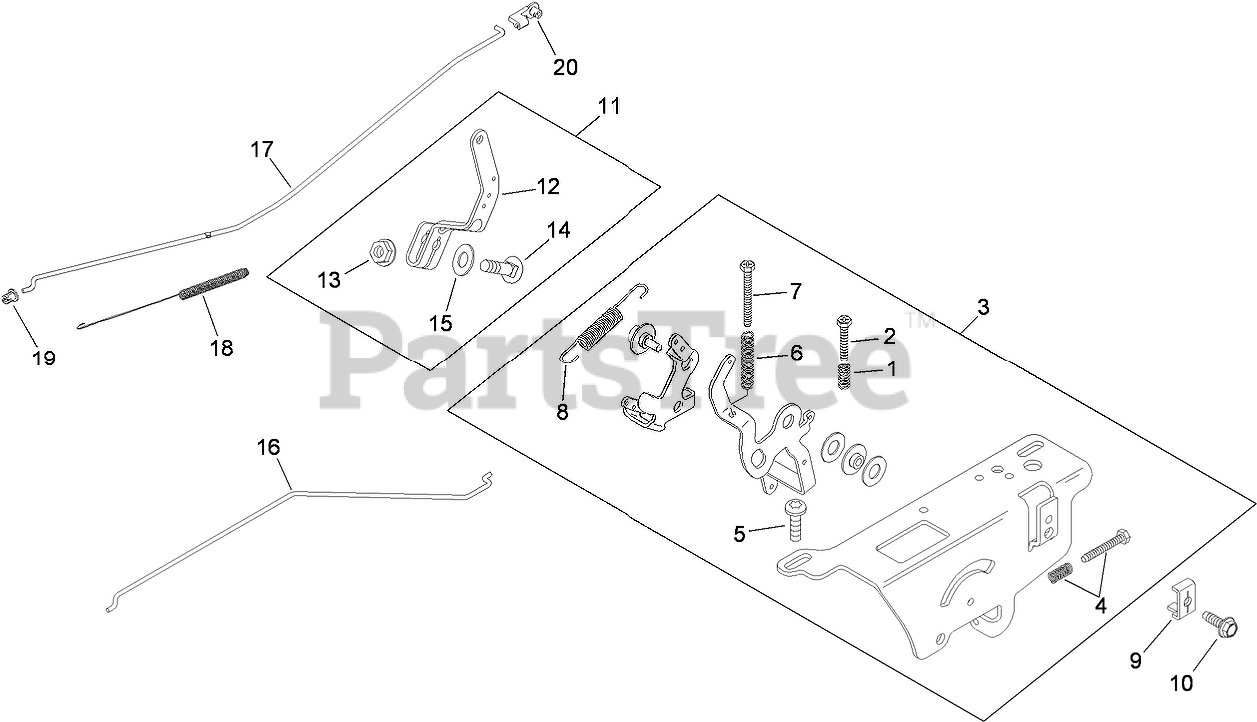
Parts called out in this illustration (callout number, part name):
1	Spring-Control, Speed
2	Screw-Thread Forming (M4x0.7x25)
3	SPEED CONTROL ASM (INCLUDES REF 1, 2, 4 QTY 1], 5, 6, 7 and 8)
4	IDLE ADJUSTING SCREW AND SPRING KIT
5	Screw-Socket, 6 Lobed (Thread Forming, M6x1.0x20)
6	SPRING-CONTROL, SPEED (LONG)
7	SCREW-PHL THD FRM (M4X0.7X38)
8	Spring-Governor
9	CLAMP-CABLE
10	SCREW-FLANGE, THREAD FORMING (M5X0.8X16)
11	GOVERNOR LEVER ASM (INCLUDES REF 12-15)
12	Lever-Governor
13	Nut-Flange, Hex (1/4-20)
14	Bolt-Square Neck, Round Head (1/4-20x1)
15	Washer-Lock, Internal Tooth (1/4)
16	Linkage-Choke (Single Wire)
17	LINKAGE-THROTTLE
18	Spring-Linkage
19	BUSHING-LINKAGE, THROTTLE
20	BUSHING-RETAINING, LINKAGE
